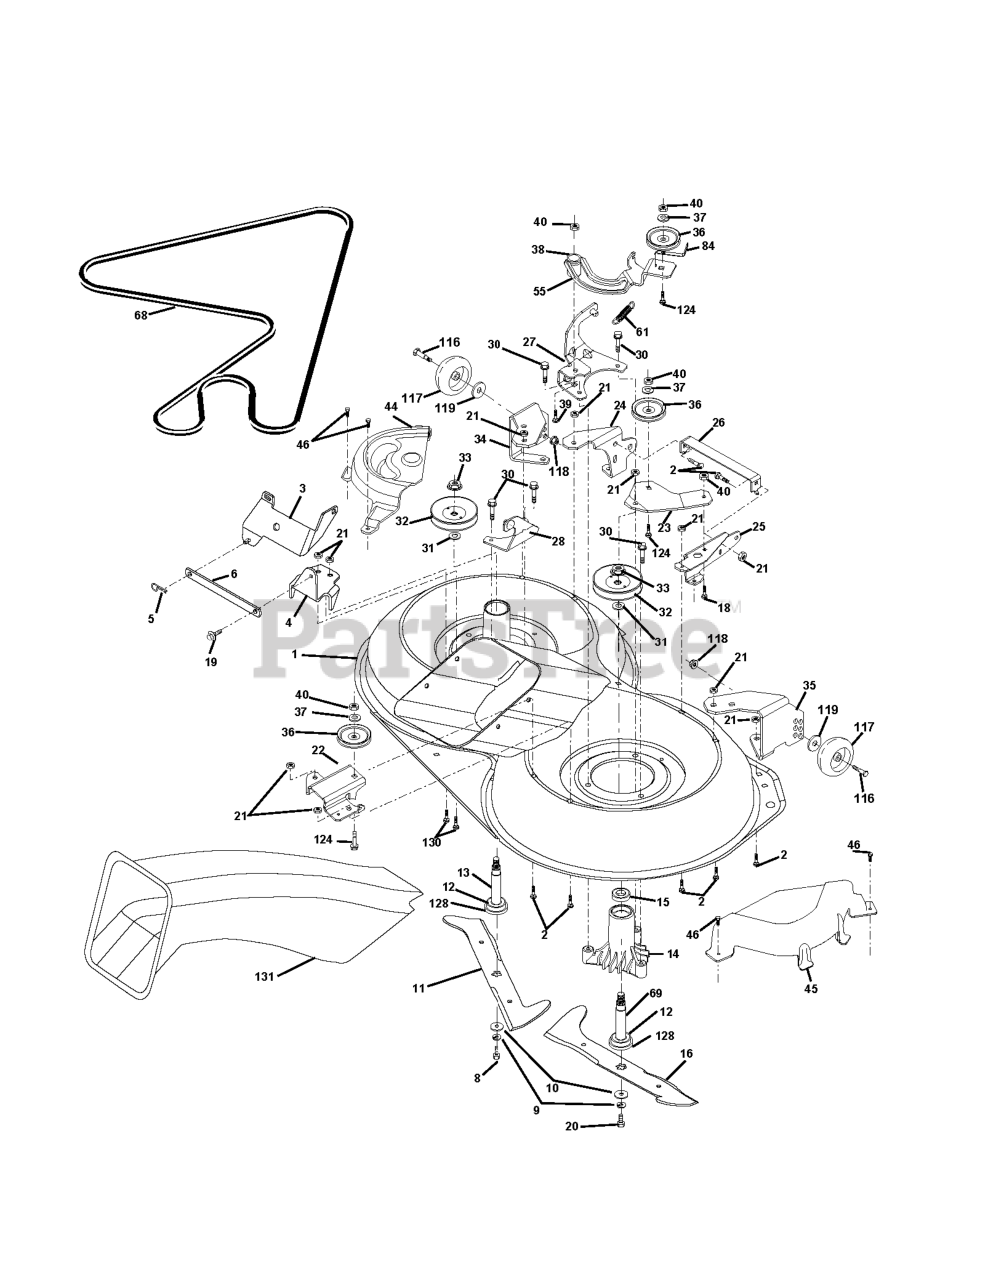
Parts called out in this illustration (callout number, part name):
1	Housing Asm. Mower 107 CRD
2	RP BOLT 5/16-18 X3/4 ZN/YEL GR
5	RETAINER-SPRNG RB
6	BAR.SWAY.92.CRD
8	BLADE BOLT
9	LOCKWASHER
10	WASHER.BLADE
11	BLADE - LH (CTH150)
12	BEARING.BALL.#6204.(MANDREL)
13	SHAFT ASM VENT
14	HOUSING.MANDREL.VENTED (MACHD)
16	BLADE - RH (CTH150)
18	BOLT D
19	BOLT SHD 5/16-18
21	LOCKNUT
22	BRACKET.IDLER.RR.107.CRD
25	BRACKET.SUSPENSION.RF.107.CRD
26	BRACE.SUPT.SUSP.FRT.CRD
28	BRACKET
30	SCREW THDROL ROLLING WASHER HD
31	WASHER
32	PULLEY/MANDREL
33	NUT
34	BRACKET
36	PULLEY.IDLER.4.25
37	WASHER
44	Cover Mandrel Lh 107 CRD
45	MANDREL COVER RH
46	SCREW.1/4-20X5/8
55	ARM.IDLER.107.CRD
56	SPACER RETAINER
61	SPRING.TENSION.BELT
68	HEX-BELT 107 MOWER
69	SHAFT.ASM.W/LWR.BRG.RH.THREAD
84	KEEPER, BELT IDLER
116	BOLT, SHOULDER
117	WHEEL GAGE DONUT
118	LOCKNUT
119	WASHER.5/16.FLAT.STE.STD.
124	BOLT.3/8-16X1.50
128	WASHER FELT
130	BOLT.CARR.SQNK.5/16-18UNC.X3/4
131	CHUTE BAGGER
